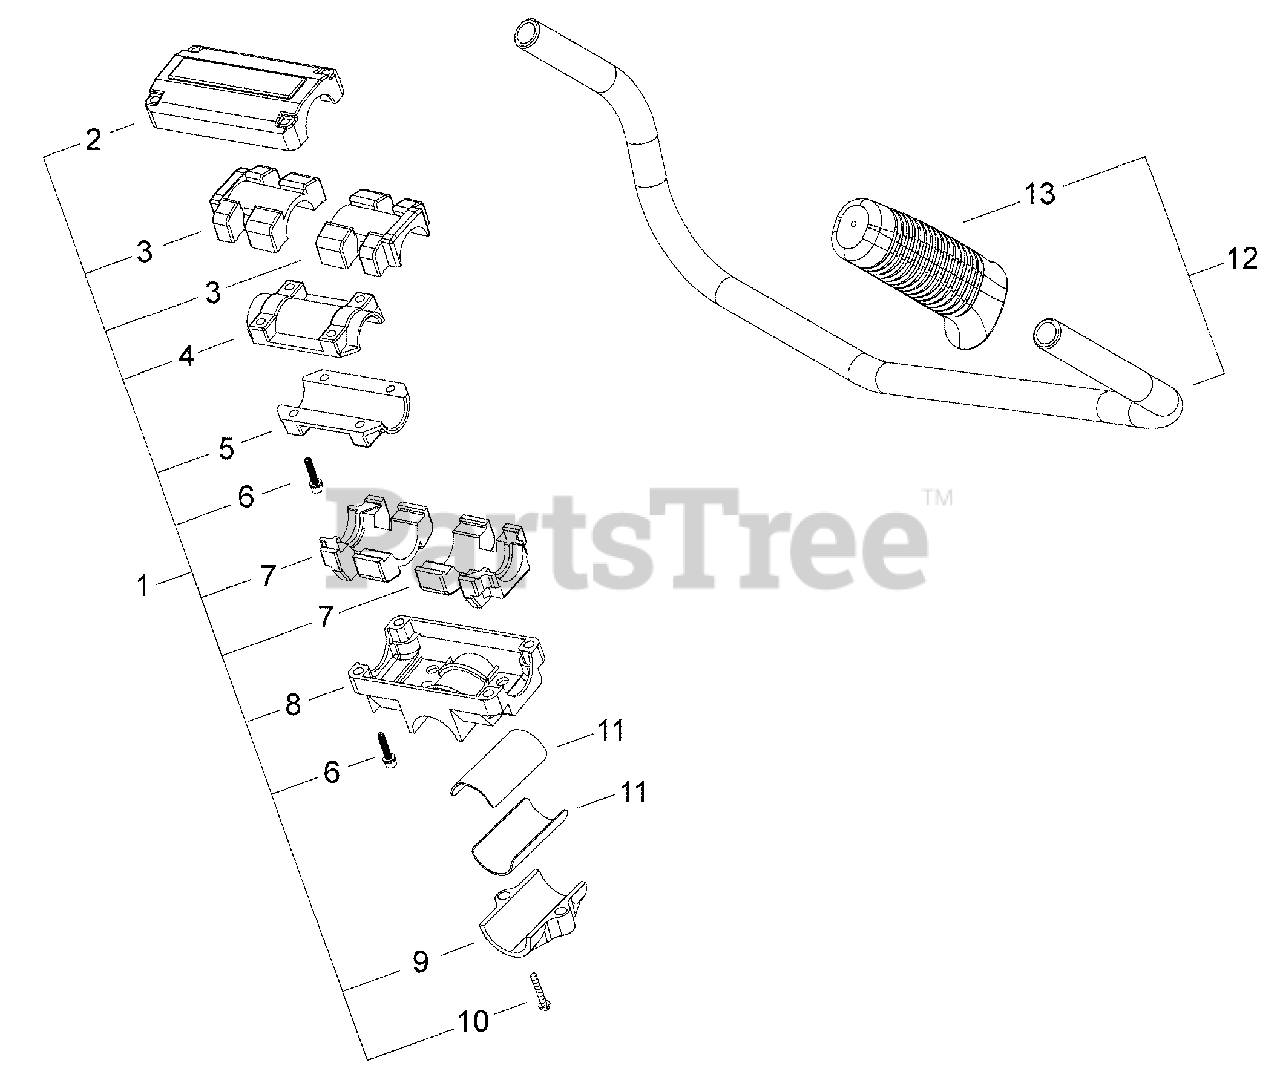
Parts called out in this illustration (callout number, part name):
1	HANDLE BRACKET KIT
2	BRACKET, HANDLE - UPPER
3	CUSHION - UPPER
4	CLAMP - UPPER
5	CLAMP - LOWER
6	SCREW - 5X25
7	CUSHION - LOWER
8	BRACKET, HANDLE - LOWER
9	BRACKET, HANDLE - UPPER
10	SCREW - 6X25
11	SPACER
12	HANDLE ASSY
13	GRIP
